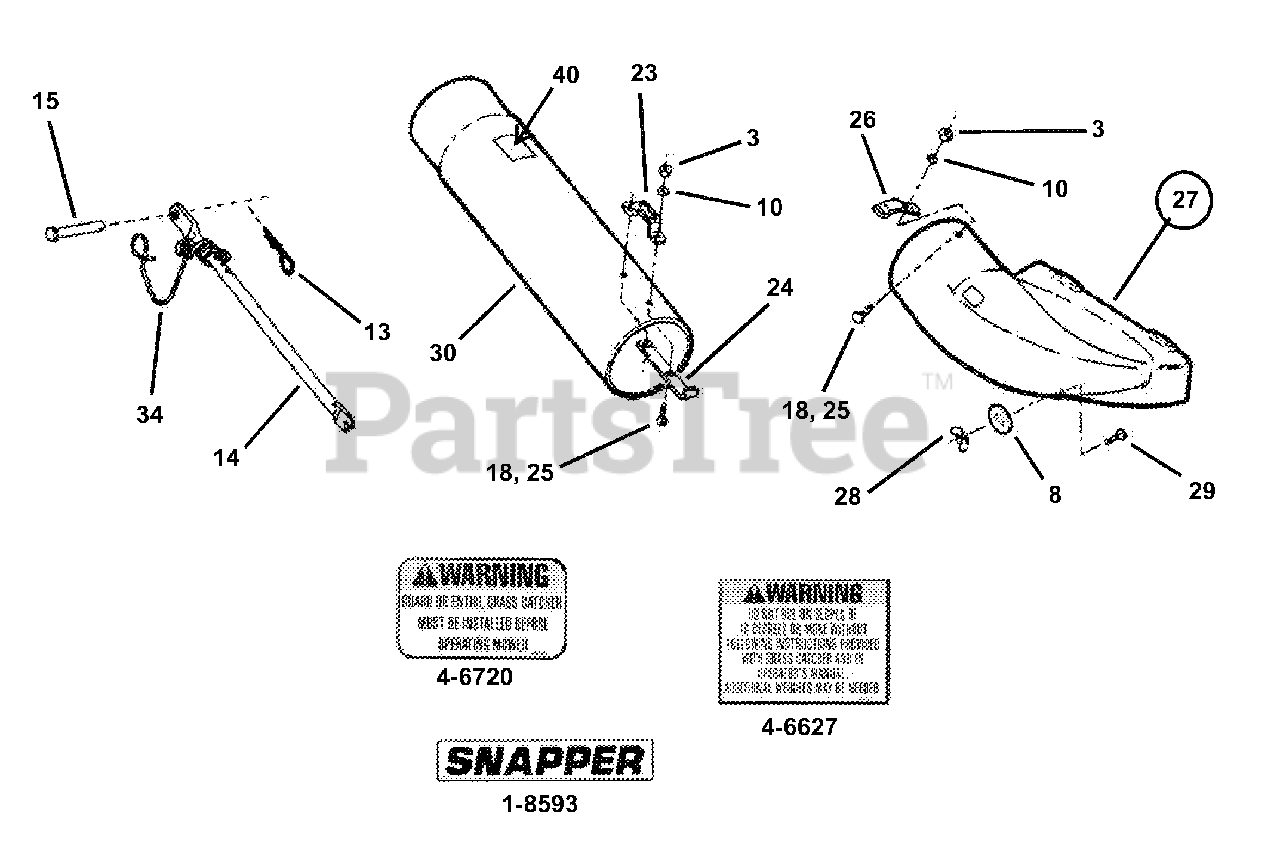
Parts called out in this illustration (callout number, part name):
1-8593	DECAL, SNAPPER
3	NUT, 1/4-20 Hex
4-6627	DECAL, GRASS BAG WARNING
4-6720	DECAL, CHUTE DEFLECTOR
8	WASHER, 11/32" Flat
10	WASHER, 1/4" Lock
13	PIN, 3/32 x 1-1/2" Hair
14	BRACE, Rear
15	PIN, 5/16 x 1-11/16" Clevis
18	BOLT, 1/4-20 x 3/4" Carriage
23	HANDLE, Tube
24	BASE, Tube Handle
25	SCREW, 1/4-20 x 3/4" Mach.
26	LATCH, Chute Tube
27	ASSY, Bag Adapter, 33"
28	WING LOCKNUT, 5/16-18
29	BOLT, 5/16-18 x 1" Carriage
30	TUBE, Grass (45" long)
34	ASSY, Spring & Hook
40	DECAL, Warning
